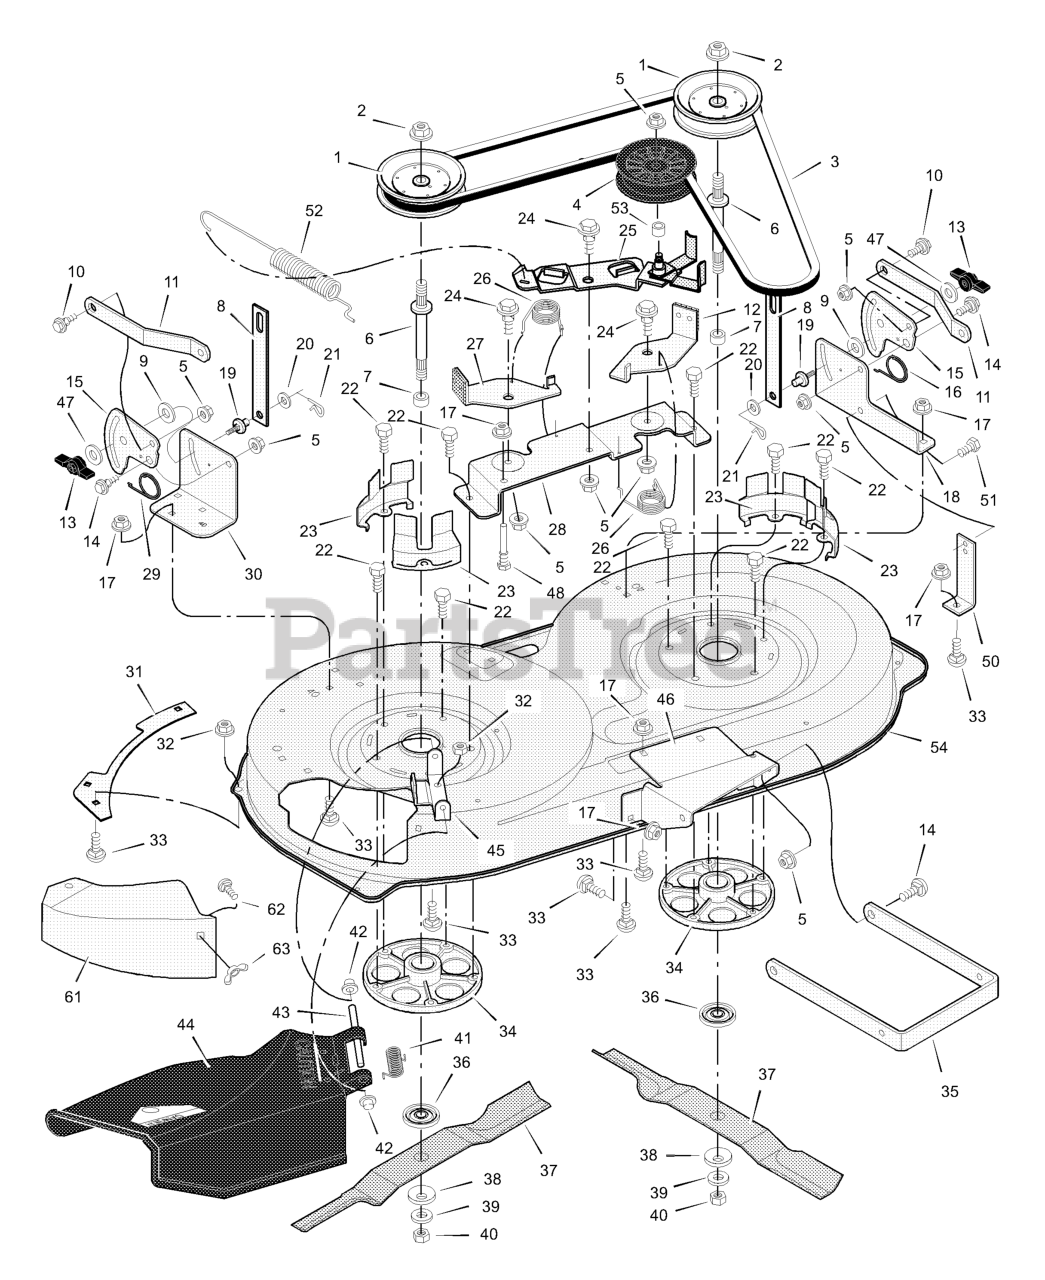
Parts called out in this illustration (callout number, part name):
1	Pulley, Jackshaft
2	Nut, Hex
3	Belt, Mower Drive
4	Pulley, Idler
5	Nut, Flange
6	Jackshaft
8	Link, Lift
9	Pad, Friction
10	Bolt, Shoulder
11	Bracket, Suspension
12	Pad Assembly, Left Brake
13	Knob
14	Bolt, Shoulder
15	Plate, Suspension
17	Nut, Flange
18	Bracket, Left Suspension
19	Pin, Hanger
21	Pin, Cotter
22	Bolt
23	Cover, Pulley
24	Bolt, Shoulder
25	Arm, Idler
27	Pad Assembly, Right Brake
28	Bracket Assembly, Brake
30	Bracket, Right Suspension
31	Plate
32	Nut, Flange
33	Bolt, Carriage
34	Mandrel
35	Bracket, Suspension
36	Adapter, Blade
42	Cap, Push On
43	ROD, Deflector
44	Deflector Assembly
45	Bracket, Deflector
46	Bracket, Front Hanger
48	Guide, Belt
50	Bracket, Support
52	Spring, Extension
54	Housing, Blade
61	Plate, Mulcher
62	Bolt, Carriage
63	Wingnut
